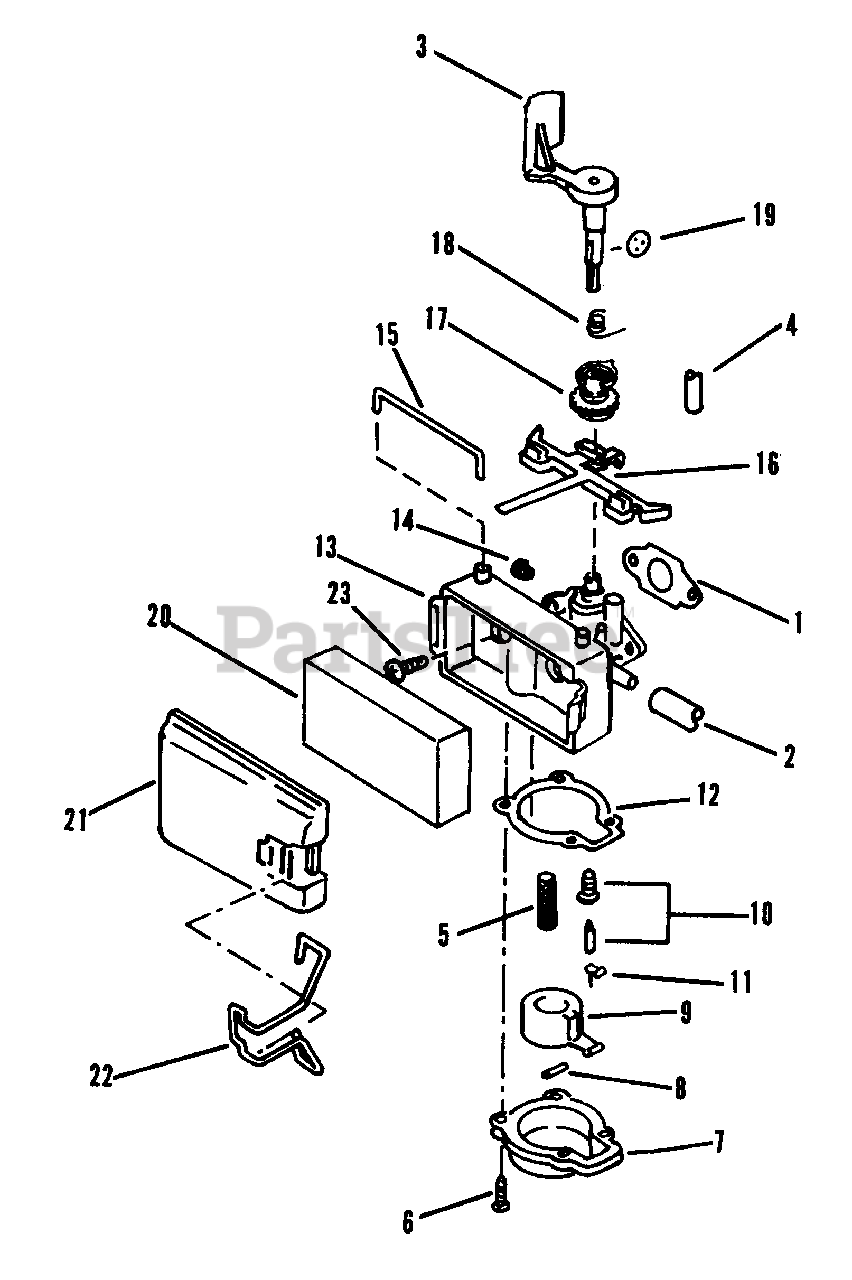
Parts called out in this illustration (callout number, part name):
1	Gasket-Carburetor to Crankcase Cover
2	Fuel Line
3	Air Vane & Shaft
4	Tube-Primer
5	Filter-Carburetor
6	Screw-Float Chamber
7	Float Chamber
8	Pin-Float
9	Float
10	Float Valve & Seat Assembly
11	Clip
12	Gasket
13	Carburetor Body
14	Screw-Altitude Adjustment
15	Retainer-Speed Control Lever
16	Speed Control Lever
17	Collar
18	Spring
19	Disk-Throttle
20	Element-Air Filter
21	Cover-Air Filter
22	Retainer-Filter Cover
23	Screw-Carburetor Mounting
